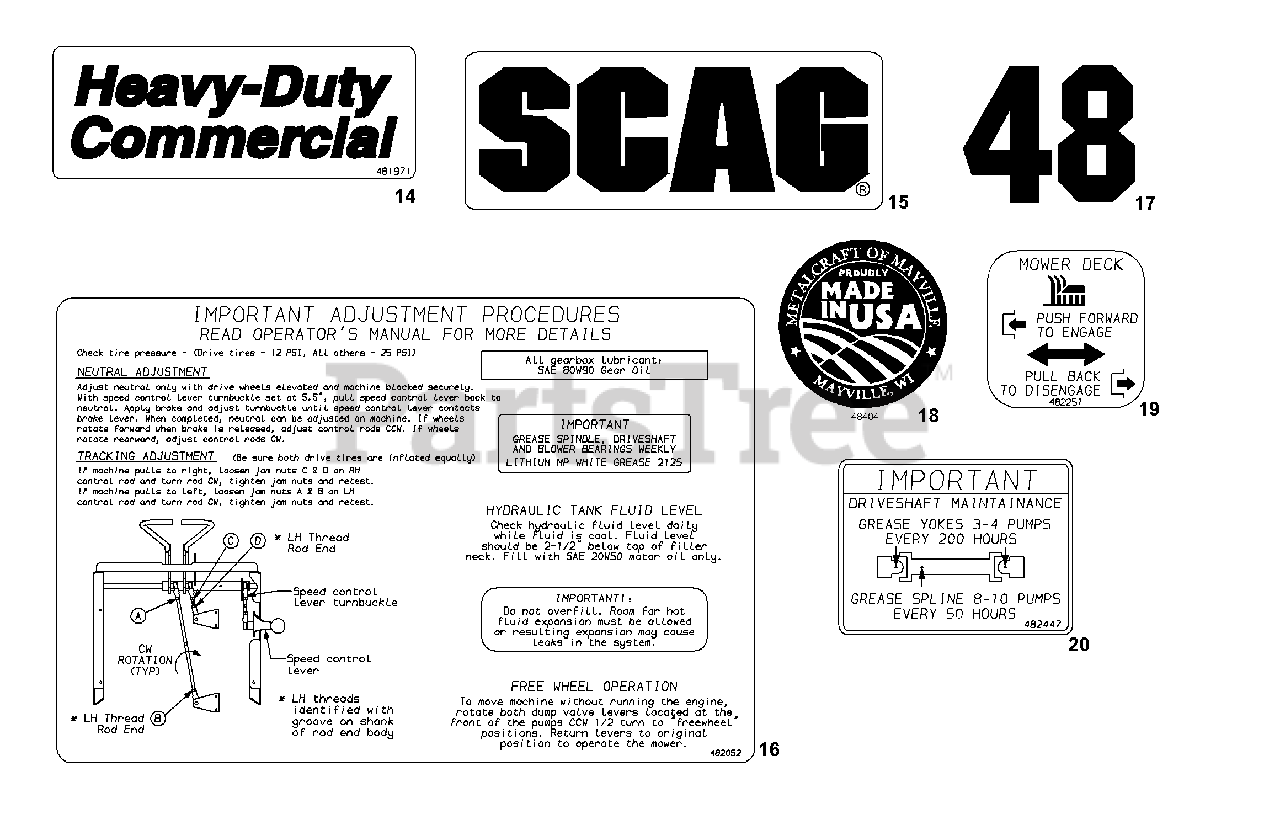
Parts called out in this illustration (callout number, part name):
14	Decal, Heavy Duty
15	Decal, SCAG
16	Decal, Adjustments
17	Decal, 42" Cutter Deck
18	Decal, Made in the USA - Metalcraft of Mayville, Inc.
19	Decal, PTO Engagement
20	Decal, Driveshaft Grease
